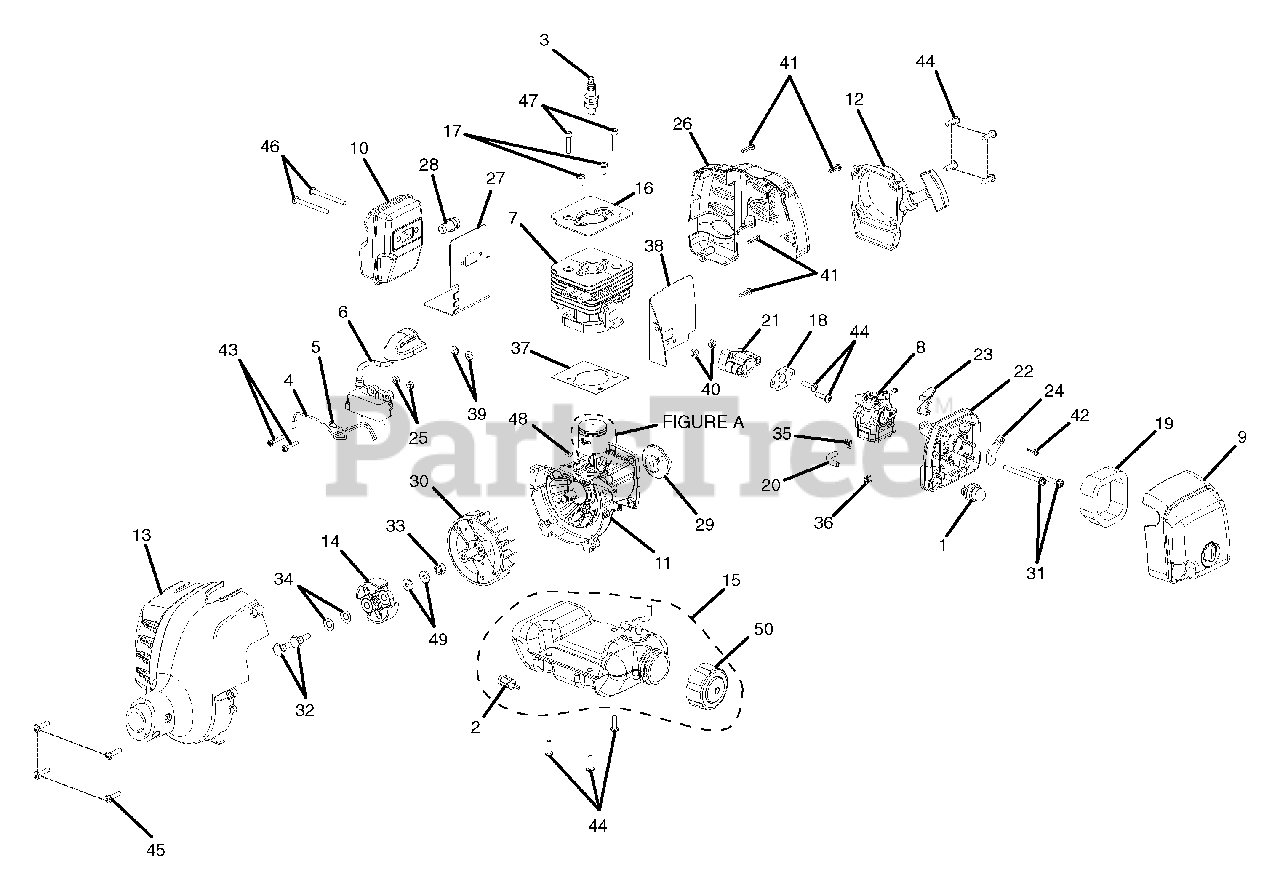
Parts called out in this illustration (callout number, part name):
1	Primer Assembly
2	Fuel Filter
3	Spark Plug
4	Lead Assembly,Black
5	Lead Assembly,Red
6	Coil, Boot, Assembly
7	Cylinder
8	Carburetor Assembly
9	Cover Assembly
10	Muffler Assembly
11	Crankcase Assembly
12	Starter Recoil Assembly
13	Front Housing Assembly
14	Clutch Assembly
15	Fuel Tank Assembly
16	Cylinder Plate
17	Screw, (M5 x 0.8x 10 in.Torx Recessed Pan HD., Machine)
18	Carburetor Gasket
20	Tubing, Plastic Rubber
21	Insulator, Heat Dam
22	Carburetor Plate
23	Choke Lever
24	Choke Plate
25	Ignition Coil Spacer
26	Engine Housing, Rear
27	Muffler Gasket
28	Spark Arrester
30	Rotor, Permanent Magnet
31	Screw (M5 x 0.8 x 60 mm, Slotted Recessed Pan HD. Machine)
32	Clutch Screw
33	Rotor Nut
34	Curved Washer
35	Hose Clip
36	Hose Clip
38	Insulator Gasket
39	Type A, Plain Washer (3/16 x 7/16 x 3/64, Steel Zink)
40	Nut, (M5 x .8 mm) Black Oxide
41	Screw (M4 x 1.75 x 16 mm, Type TT, Slotted Recessed Pan)
42	Screw (M4 x 1.75 x 12 mm, Type TT, Slotted Recessed Pan)
43	Screw (M4 x 0.7 x 22 mm, Torx Recessed Pan HD. Machine)
44	Screw (M5 x 0.8 x 16 mm, Torx Recessed Pan HD. Machine)
45	Screw (M5 x 0.8 x 20 mm, Torx Recessed Pan HD. Machine)
46	Screw (M5 x 0.8 x 50 mm, Torx Recessed Pan HD. Machine)
47	Screw (M5 x 0.8 x 22 mm, Socket Head Cap, Black Oxide)
48	Woodruff Key (10 mm x 3.7 mm x 3 mm)
50	Fuel Cap
